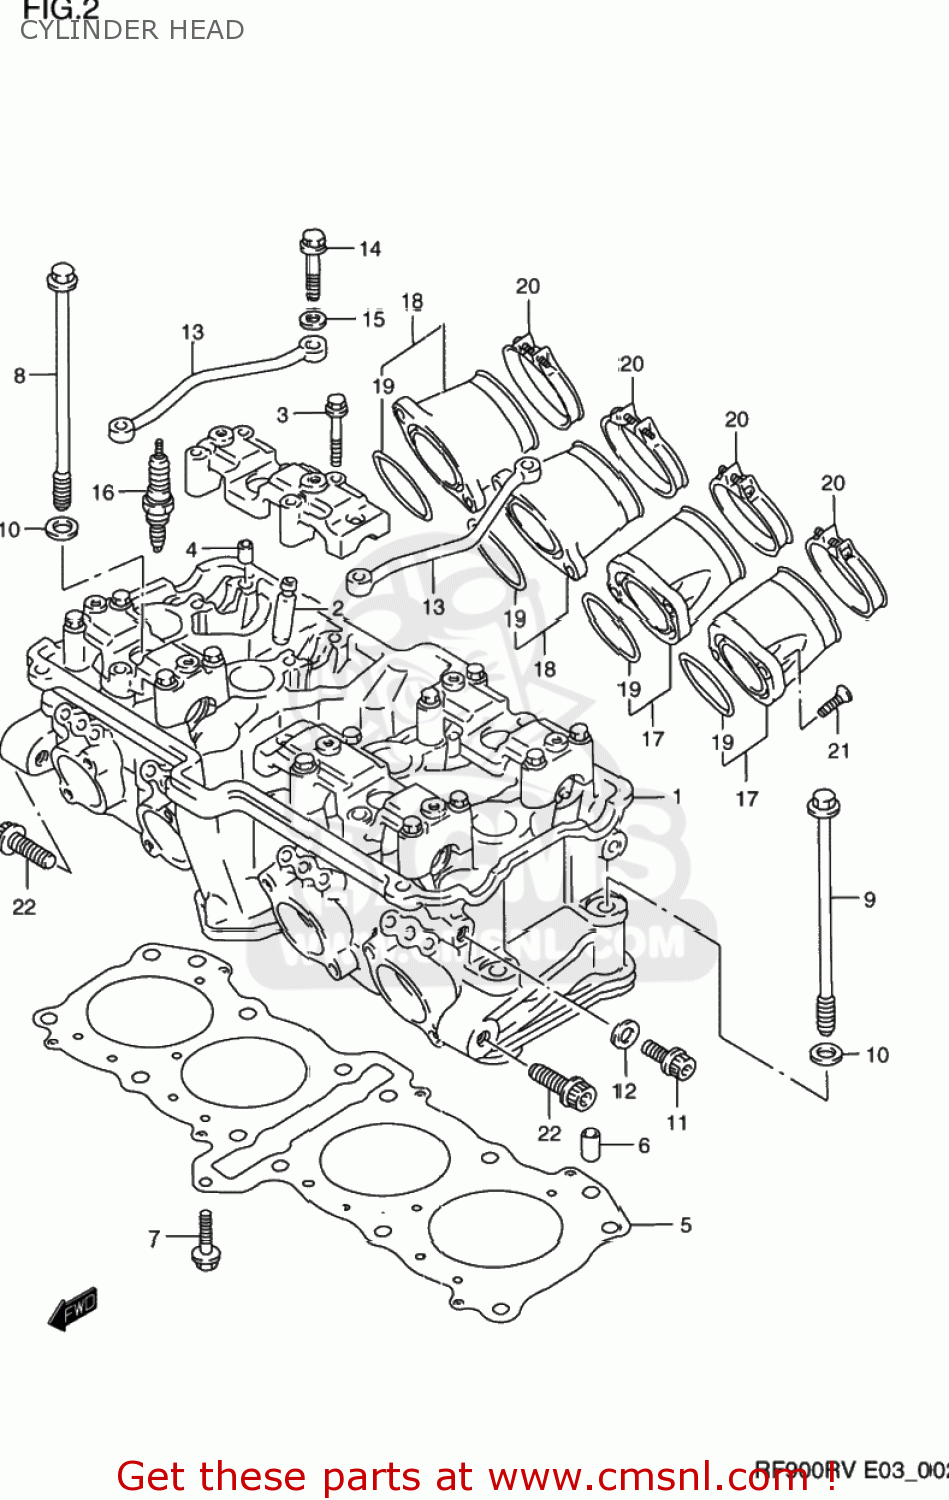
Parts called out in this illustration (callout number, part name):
1	HEAD ASSEMBLY,CYLINDER
2	GUIDE,VALVE
3	BOLT(6X45)
4	PIN(6.2X8X11)
5	GASKET,CYLINDER HEAD
6	PIN
7	BOLT
8	BOLT 10X175
9	BOLT(10X175)
10	WASHER(10.5X19X2)
11	BOLT
12	GASKET(8.2X14X1).6 (NAS)
13	PIPE,CYLINDER HEAD OIL
14	BOLT(6X39)
15	WASHER
16	PLUG,SPARK(CR8E)
17	PIPE ASSEMBLY,INTAKE
18	PIPE ASSEMBLY,INTAKE
19	O RING(D:2.4,ID:41.7)
20	CLAMP
21	SCREW
22	BOLT
